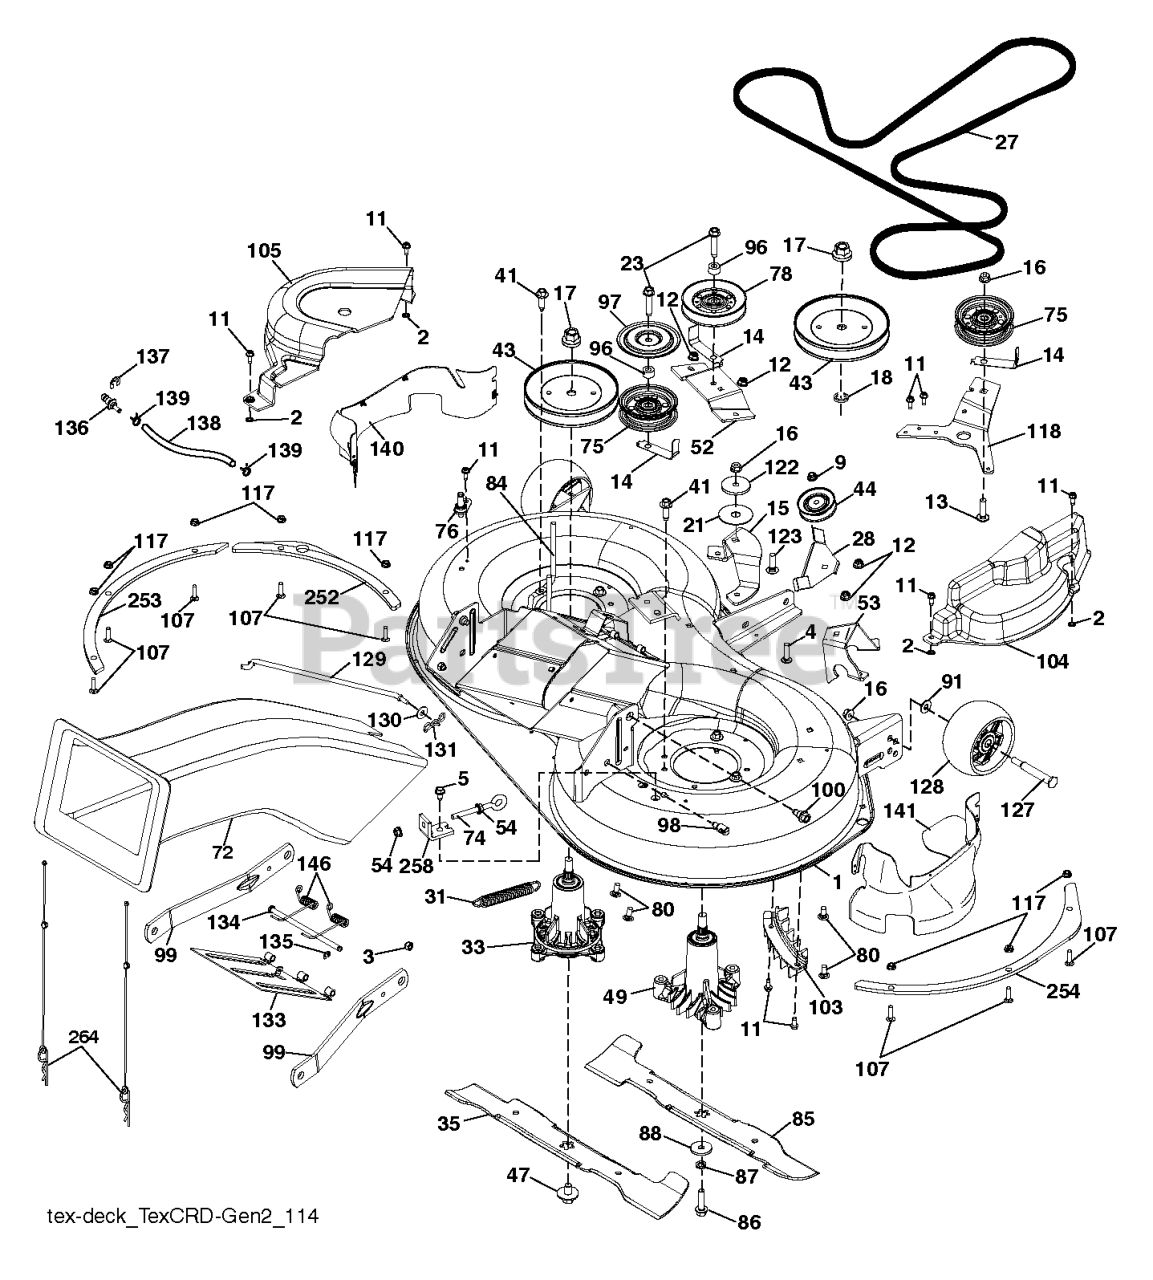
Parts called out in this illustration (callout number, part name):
1	Service Kit
2	PALNUT 1/4
3	NUT LOCK HEX FLANGE 5/16-18
4	BOLT.CARRIAGE.5/16-18
5	BOLT.5/16HEX.WHS.HD
9	NUT HEX FLG NYLOCK BLK 5_16-1
11	SCREW.1/4-20X5/8
12	5/16-18 NYLOC FLANGE NUT
13	BOLT.3/8-16X1.50
14	KEEPER, BELT IDLER
15	BRACKET CRD IDLER ARM MOUNT BL
16	NUT LOCK FLG 3/8-16 UNC
17	NUT.FLANGE.LOCK.TOP
18	WASHER.SPACER.MANDREL
23	SCREW LT
27	BELT.97CRD.ELECTRIC.DECK.DRIVE
28	KEEPER 97 CRD ANGLED IDLER KEE
31	SPRING.EXTN.42.FCS.TR.DECK.DRV
33	KIT.MANDREL.NONGREASE.TALL
35	BLADE.3N1.LH.CRD.97
41	BOLT.HEX.WASHR.HED.313-18X1.19
43	PULLEY.MANDREL.5.0.PD.38"
44	PULLEY.V-IDLER.
47	SCREW.SEMS.7/16-20X1.HEX.HEAD
49	MANDREL ASM.CRD RH 6PT STAR
52	BRACKET 97 CRD CENTER V-IDLER
53	BRACKET 97 CRD ANGLED V-IDLER
54	NUT 5/16C WHIZ
72	CHUTE.SLOTTED.HOLES.TEX.CRD.II
74	EYE BOLT 5/16 X 3.50
75	PULLEY.IDLER.FLAT
76	1/2" BARB.DECK.WASHOUT.PORT
78	REPL BY 532 1467-63
80	BOLT 5/16C X 3/4" CARRIAGE
84	BELT KEEPER.MANDREL.38"COATED
85	BLADE.3N1.RH.CRD.97
86	BOLT.3/8-24X1.25GR8. LHTHRD
87	SLW 3/8 STD
88	WASHER.BLADE
91	WASHER.5/16.FLAT.STE.STD.
96	SPACER
97	PROTECTOR
98	STUD.FASTNER.W/ANTI-ROTATE
99	ARM.SUSPENSION.MOWER.R
100	BOLT.SHOULDER
103	GUARD GUARD FRONT VENT
104	GUARD 97CRD RH MANDREL COVER;
105	MANDREL MANDREL COVER LH
107	BOLT CUP HEAD SQUARE NECK 1/4-
117	NUT T
118	ARM 97 CRD IDLER ARM BLACK E-C
122	SPACER.RETAINER.MOWER
123	BOLT
127	BOLT.SHOULDER.3/8-16X3-5/8.
128	WHEEL.GAUGE.RALLY
129	ROD ROD. SWAY CRD GEN II
130	WASHER
131	PIN.COTTER.5/16.BOW TI
133	DOOR
134	PIN PIN.HINGE
135	E-RING.5/16"
136	PLUG WASHOUT PORT HOOKUP
138	HOSE.3/8ID.BULK.12"
139	HOSE.3/8.CLAMP (2 2)
140	GUARD.ASSEMBLY.97.LH.FRENCH
141	GUARD.ASSEMBLY.97.RH.FRENCH
146	SPRING SPRING: EZ MULCH DOOR
252	PLATE.REINFORCEMENT.X431
253	PLATE.REINFORCEMENT.LHS.X431
254	PLATE.REINFORCEMENT.LHS.X431
258	BRACKET CRD ELEC DECK DRIVE TE
264	RETAINER.ASM.UPPERCHUTE.CRD2.5
